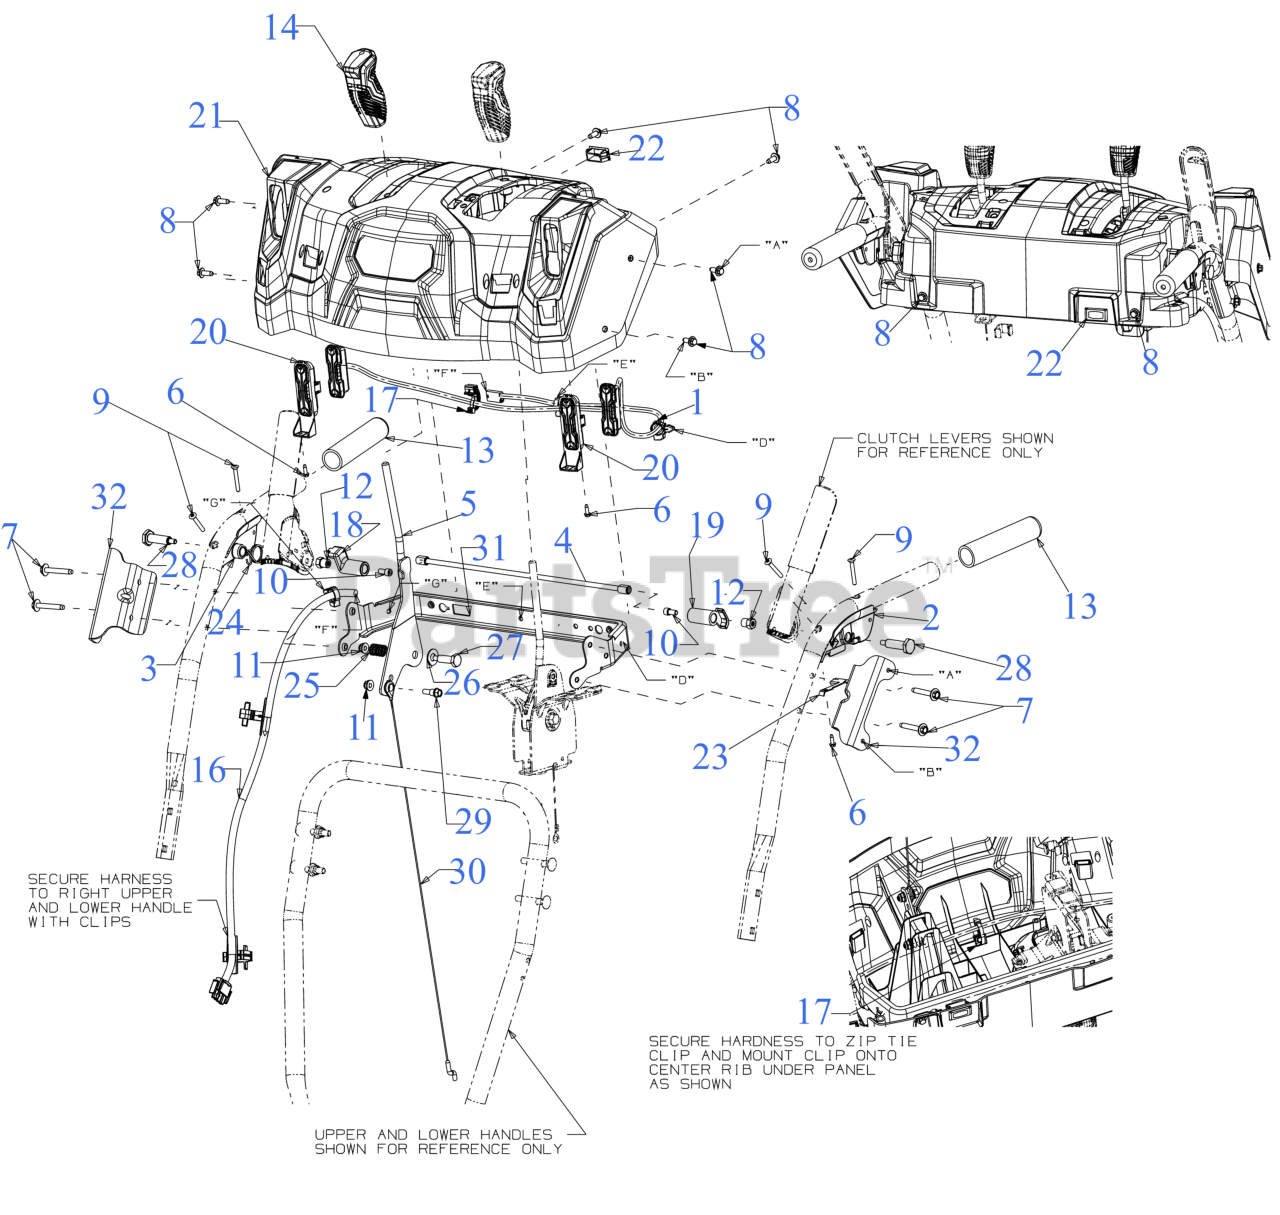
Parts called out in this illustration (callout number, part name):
1	HEADLIGHT HARNESS (W/LED)
2	CLUTCH LOCK HANDLE ASSEMBLY (LH)
3	CLUTCH LOCK HANDLE ASSEMBLY (RH)
4	PIVOT ROD
6	SCREW #8-16 x .50
7	SCREW 1/4-20 x 1.625
8	SCREW M6-1 x .625
9	SCREW #10-24 x 1.375
10	SCREW 1/4-20 x .50
11	FLANGE LOCK NUT
12	HEX NUT W/PATCH
16	LED HEADLIGHT HARNESS
17	EDGE MOUNT ZIP TIE CLIP
18	LOCK PLATE
19	CLUTCH LOCK CAM
20	LENS BEZEL
21	HEADLIGHT PANEL
22	SWITCH PLUG
23	CLUTCH SPRING
24	TORSION SPRING
25	COMPRESSION SPRING
26	FLAT WASHER .38X.88
26	FLAT WASHER .401X.88
27	SHOULDER SCREW
28	SHOULDER SCREW .437 x 1.345 1/4-20
29	SHOULDER SCREW .342X.335X1/4-20
30	SELECTION CABLE
